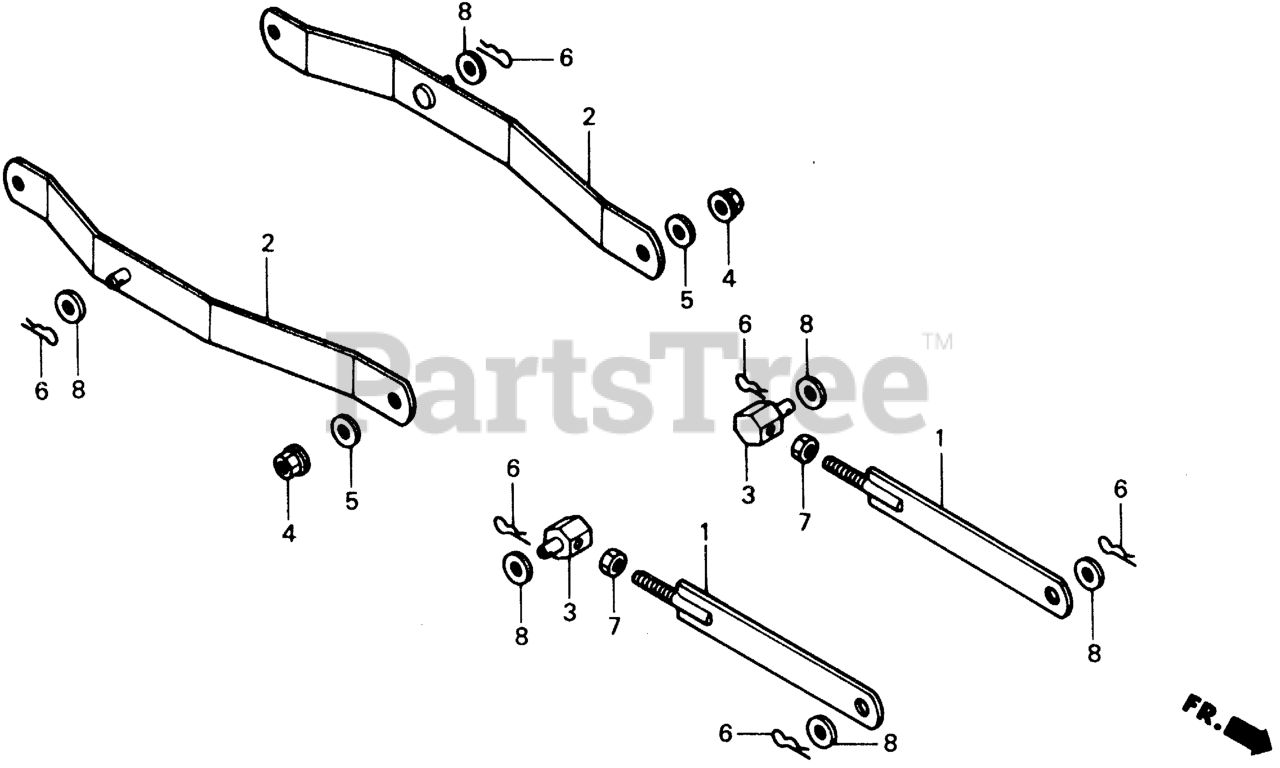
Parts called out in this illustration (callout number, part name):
1	LINK, FR. DECK
2	LINK, RR. DECK
3	PIN, FR. LINK ADJUSTING
4	NUT, U (10MM) (FUSE RASHI)
5	WASHER (10.5X27X4)
6	PIN, LOCK (14MM)
7	NUT, HEX. (12MM)
8	WASHER, PLAIN (14MM)
